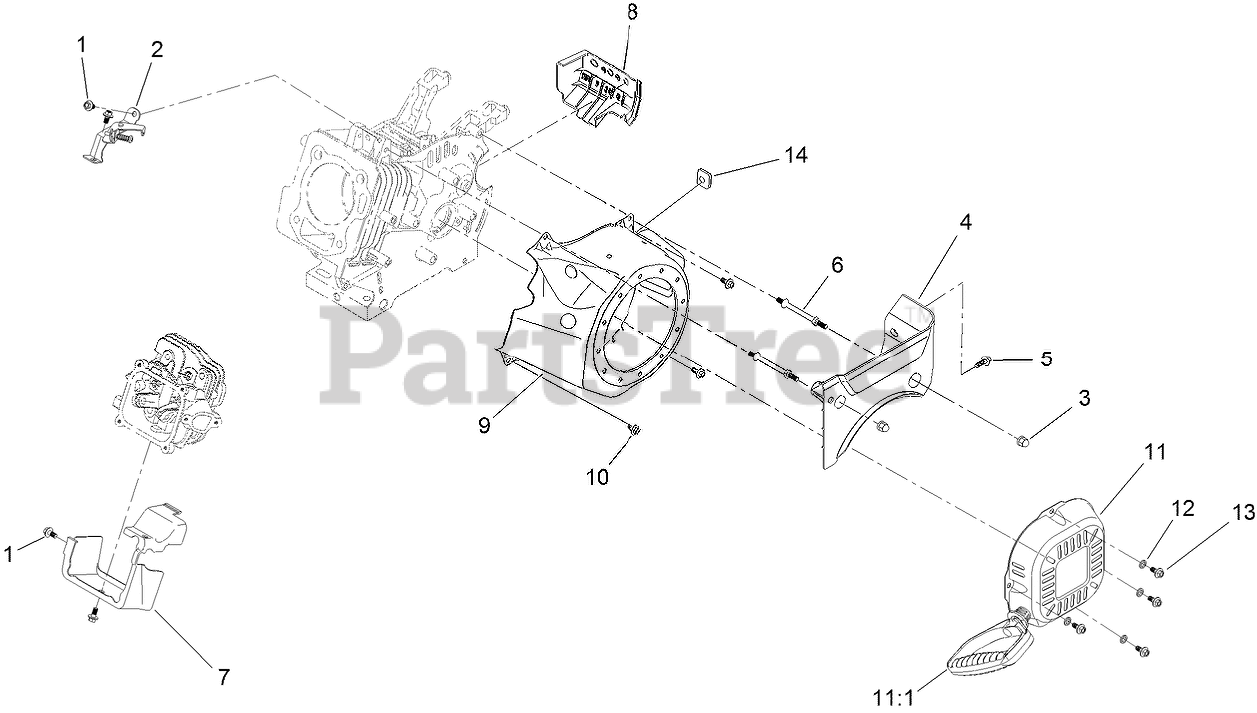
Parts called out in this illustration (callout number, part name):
1	SCREW-HHF
2	THROTTLE CONTROL ASM
3	NUT-ACORN
4	PANEL-FRONT
5	SCREW-HHF
6	STUD-MOUNT
7	SHROUD-HEAD
8	PANEL-SIDE, ENGINE
9	SHROUD-FLYWHEEL
10	SCREW-HHF
11	RECOIL ASM
11:1	HANDLE-RECOIL
12	WASHER-PLAIN
13	SCREW-HHF
14	GROMMET-RUBBER
